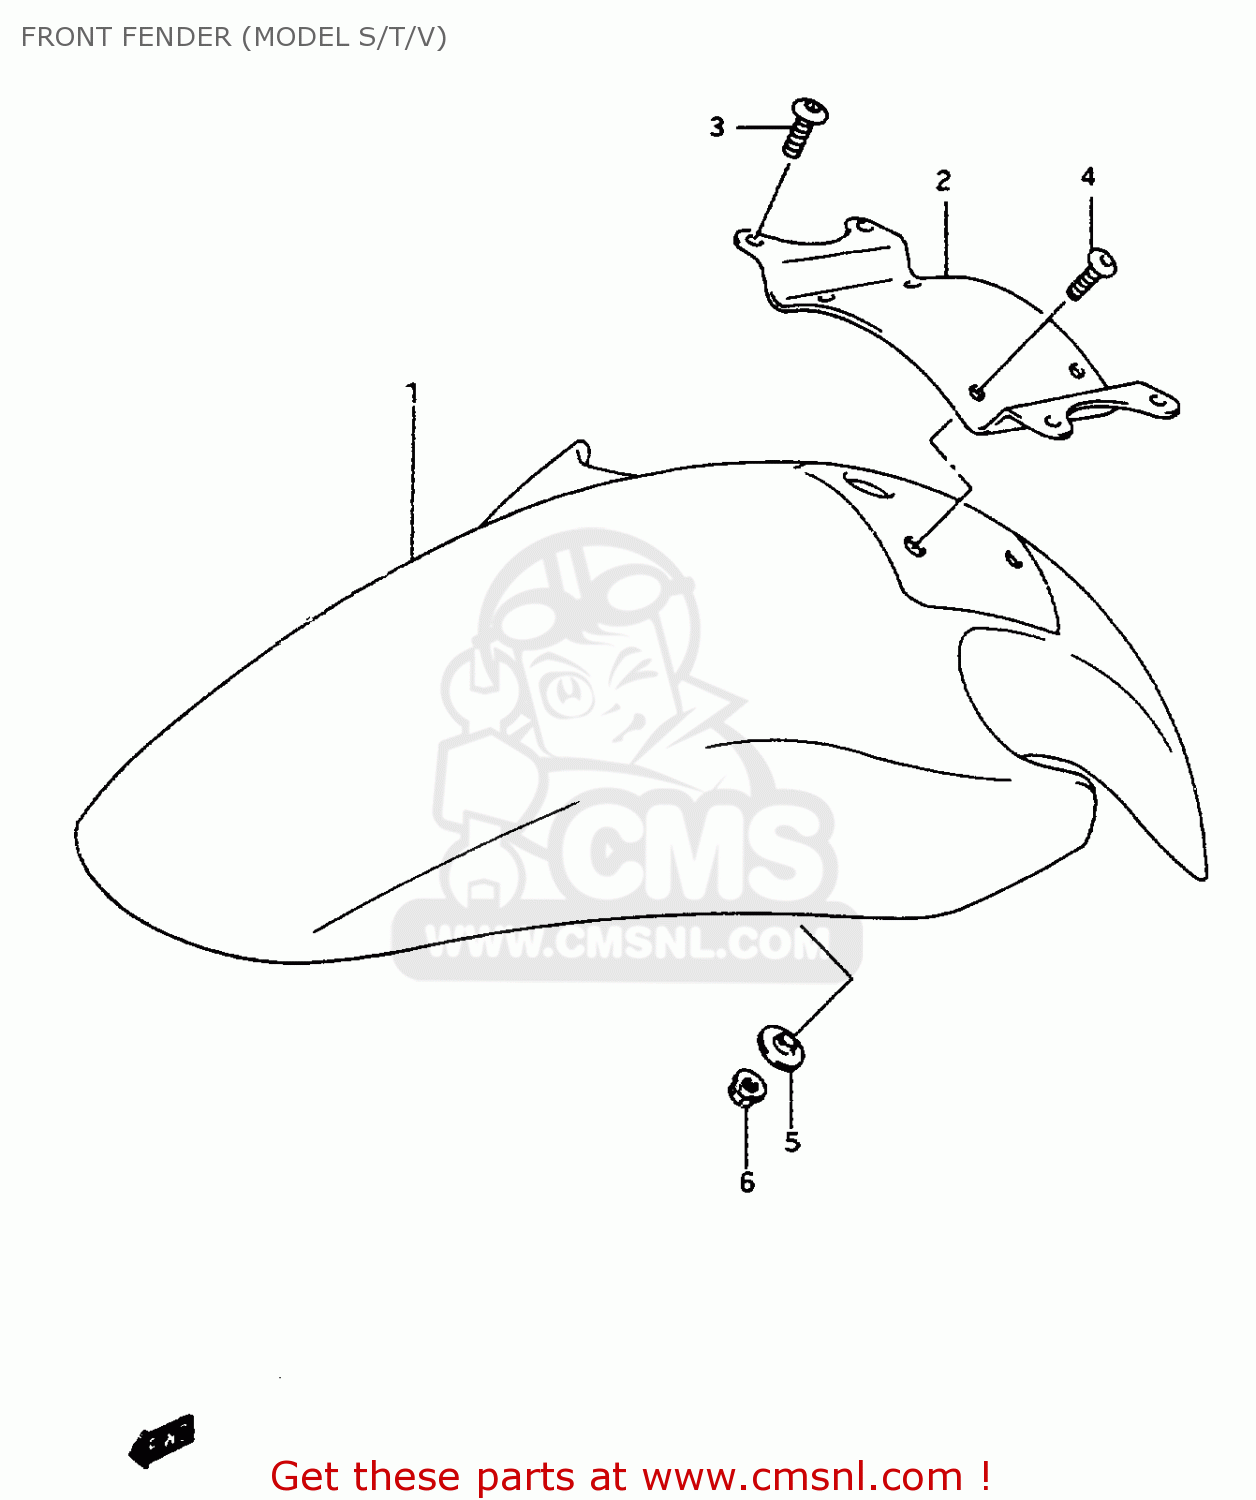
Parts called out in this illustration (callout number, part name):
1	FENDER SET,FR
2	BRACE,FR FENDER
3	SCREW(6X12)
4	SCREW(5X16)
5	WASHER
6	NUT
